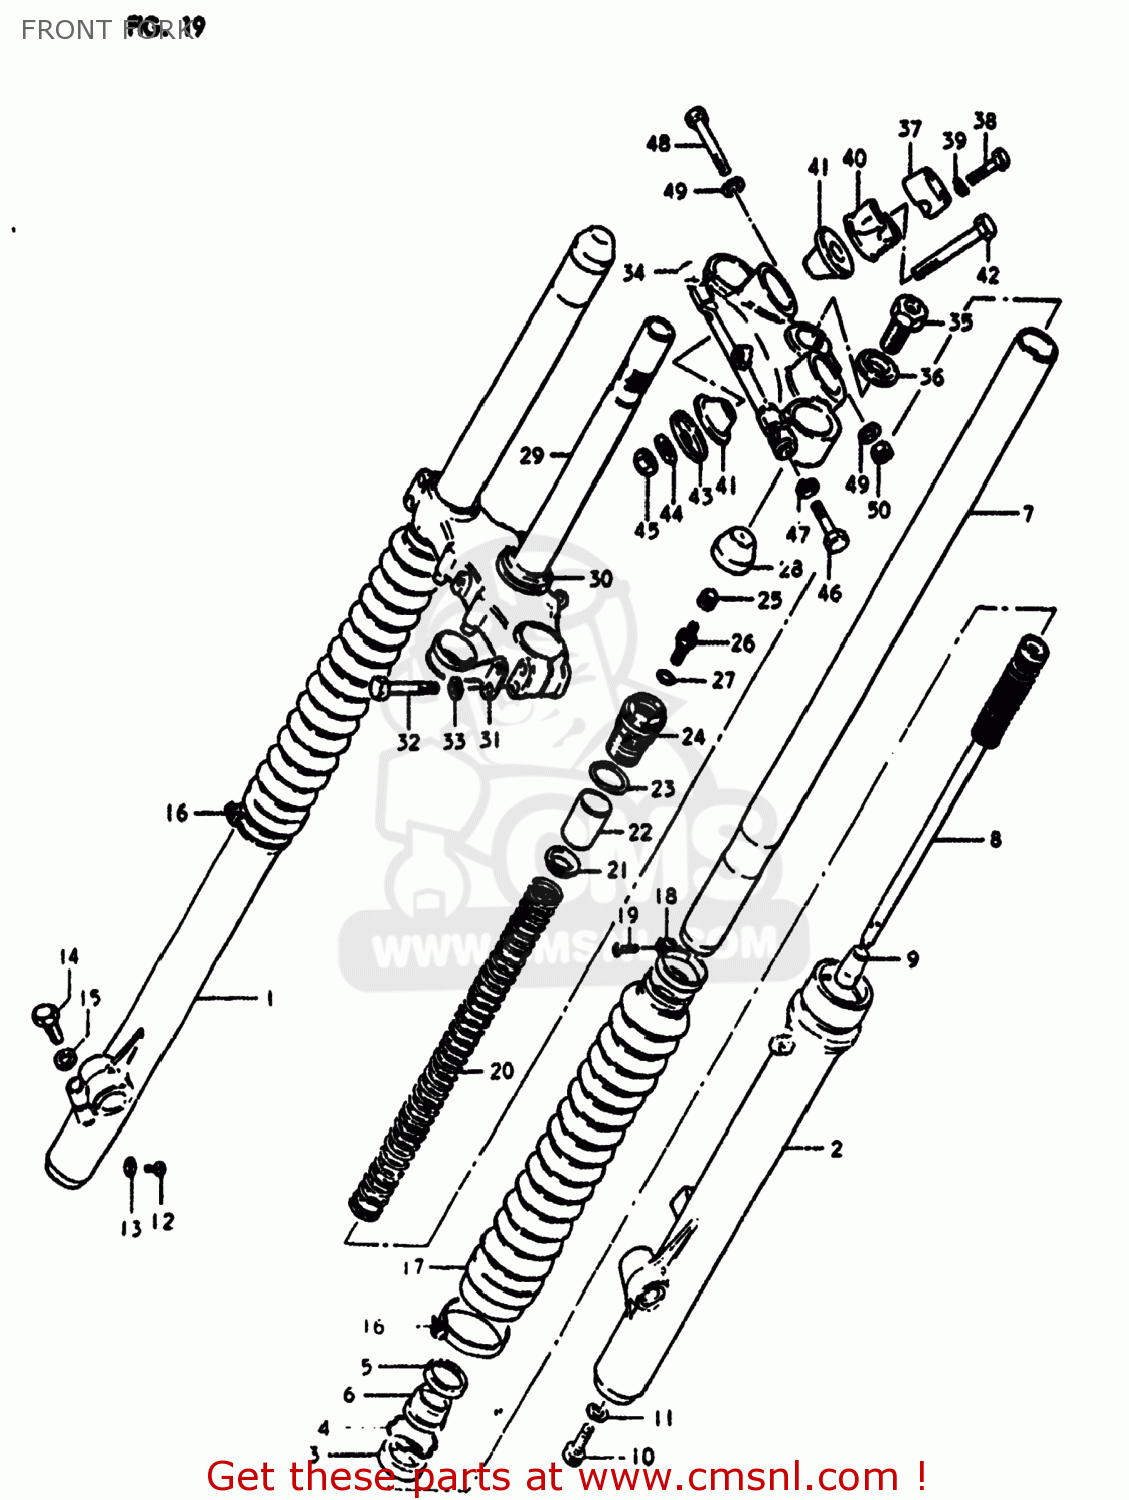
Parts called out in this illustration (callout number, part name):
1	TUBE,OUTER,RIGHT
2	TUBE,OUTER,LEFT
3	SEAL,OIL
4	RING,STOPPER
5	CASE,DUST SEAL
6	SEAL,DUST
7	TUBE,FORK,INNER
8	CYLINDER,FRONT FORK
9	PIECE,OIL LOCK
10	BOLT,CYLINDER
11	GASKET,CYLINDER (NAS)
12	SCREW
13	GASKET,DRAIN,PLUG (NAS)
14	BOLT (8X30)
15	LOCK WASHER
16	BAND,FRONT FORK COVER BOOT
17	BOOT
18	BAND,BOOT
19	SCREW 4X10
20	SPRING
21	GUIDE
22	COLLAR,SPRING
23	O RING
24	CAP,FORK INNER TUBE
25	CAP,VALVE AIR
26	VALVE
27	O RING
28	CAP
29	STEM,STEERING
30	RACE,STEERING,OUTER,UPPER
31	GUIDE,CABLE
32	BOLT 8X45
33	LOCK WASHER
34	HEAD,STEERING STEM
35	BOLT
36	WASHER
37	HOLDER,HANDLEBAR
38	BOLT
39	LOCK WASHER
40	HOLDER,HANDLEBAR,LOWER
41	CUSHION,HANDLE HOLDER
42	BOLT,HANDLE HOLDER
43	COVER,HANDLEBAR HOLDER
44	WASHER,HANDLEBAR HOLDER
45	NUT
46	BOLT
47	LOCK WASHER
48	BOLT 8X50
49	WASHER
50	NUT
